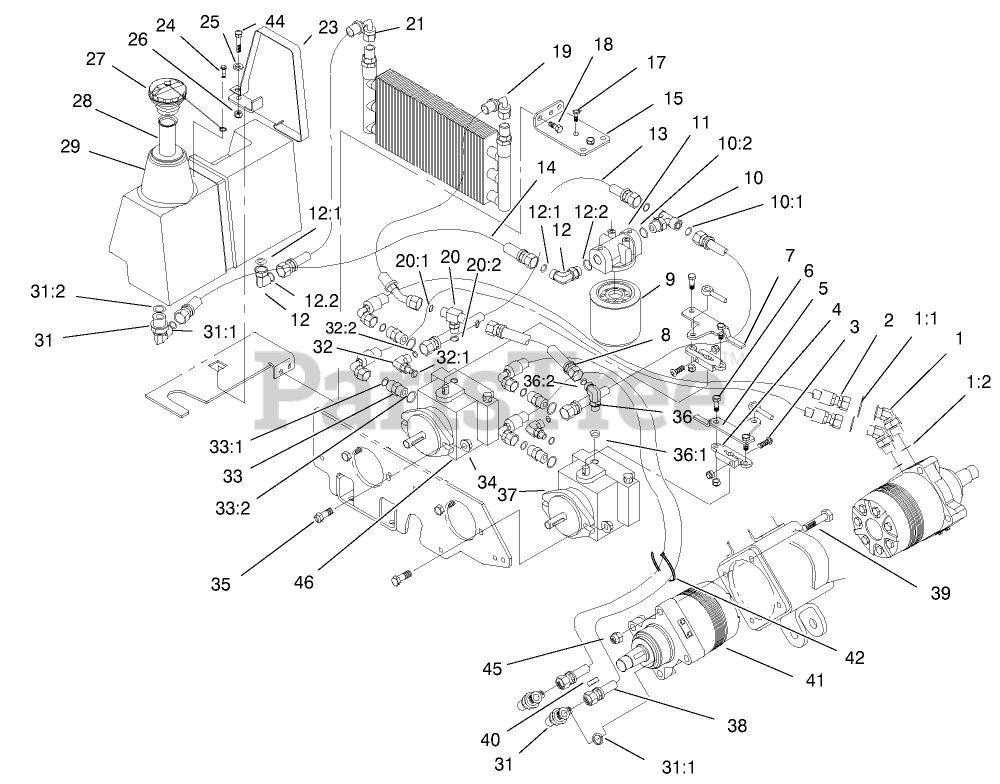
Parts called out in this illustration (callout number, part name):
1	FITTING-HYD, 45 DEG
1:1	O-RING
1:2	O-RING
2	HOSE-HYDRAULIC
3	SCREW-HSH
4	ARM-CONTROL, PUMP
5	PLATE-CONTROL, RIGHT
6	SCREW-HH
7	PLATE-CONTROL, LEFT
8	HOSE-HYD
9	CARTRIDGE-FILTER, OIL
10	FITTING-HYD, TEE
10:1	O-RING
10:2	O-RING
11	HEAD-FILTER
12	FITTING-ELBOW-90 DEG
12:1	O-RING
12:2	O-RING
13	HYDRAULIC HOSE ASM
14	HYDRAULIC HOSE ASM
15	ANGLE-MOUNT, HYD FILTER
17	SCREW-HHF
18	SCREW-HWHTF
19	HYDRAULIC HOSE ASM
20	ADAPTER
20:1	O-RING
20:2	O-RING
21	HYDRAULIC HOSE ASM
23	STRAP-TANK, HYD
24	SCREW-HWH
25	WASHER-PLAIN
26	NUT-LOCK, NI
27	CAP-OIL
28	FILTER-SCREEN
29	TANK-HYD
31	FITTING-ELBOW 90
31:1	O-RING
31:2	O-RING
32	FITTING-ELBOW 90
32:1	O-RING
32:2	O-RING
33	FITTING-STRAIGHT
33:1	O-RING
33:2	O-RING
34	NUT-HF
35	SCREW-HH
36	FITTING-ELBOW, 90 DEG
36:1	O-RING
36:2	O-RING
37	PUMP - HYDRAULIC
38	HYDRAULIC HOSE ASM
39	SCREW-HSH
40	KEY-WOODRUFF
41	MOTOR - HYDRAULIC WHEEL
42	TIE-CABLE
44	SCREW-HH
45	NUT-LOCK, NI
45	SEAL KIT
46	PUMP - HYDRAULIC
